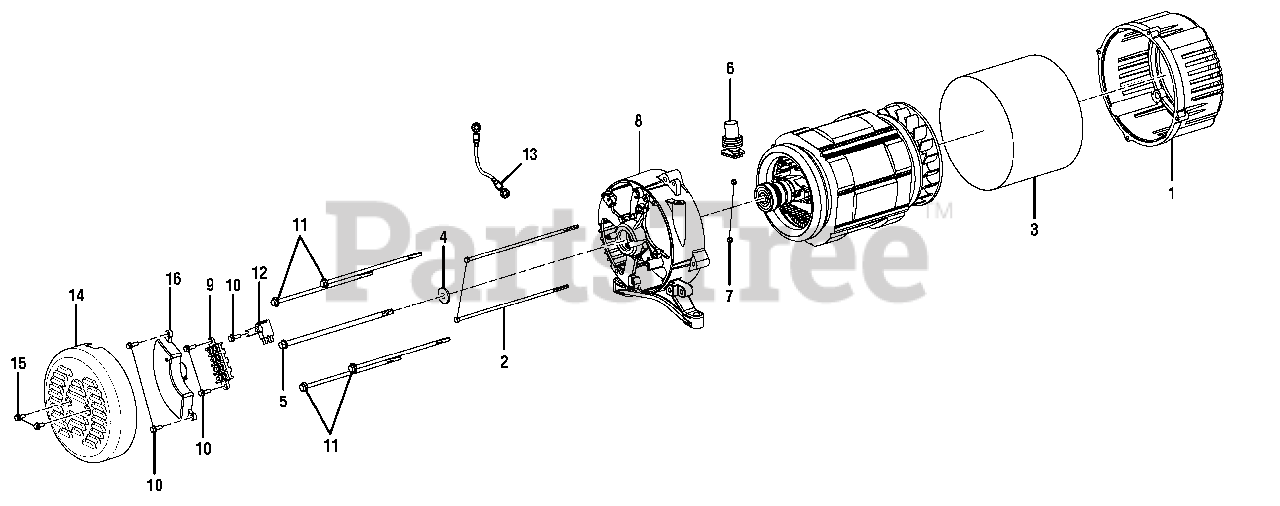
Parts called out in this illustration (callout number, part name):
1	Adaptor Housing
2	Bolt (M5, Hex Hd.)
3	Generator Head Cover
4	Lock Washer (5/16 in.)
5	Rotor Bolt (170 mm)
6	Rubber Boot
7	Hex Nut (M5)
8	Bearing Housing
9	Terminal Block
10	Bolt (M5 x 16 mm)
11	Stator Bolt (170 mm)
12	Brush Assembly
13	Bonding Wire
14	Brush Cover
15	Bolt (M5 x 12 mm)
16	Automatic Voltage Regulator
